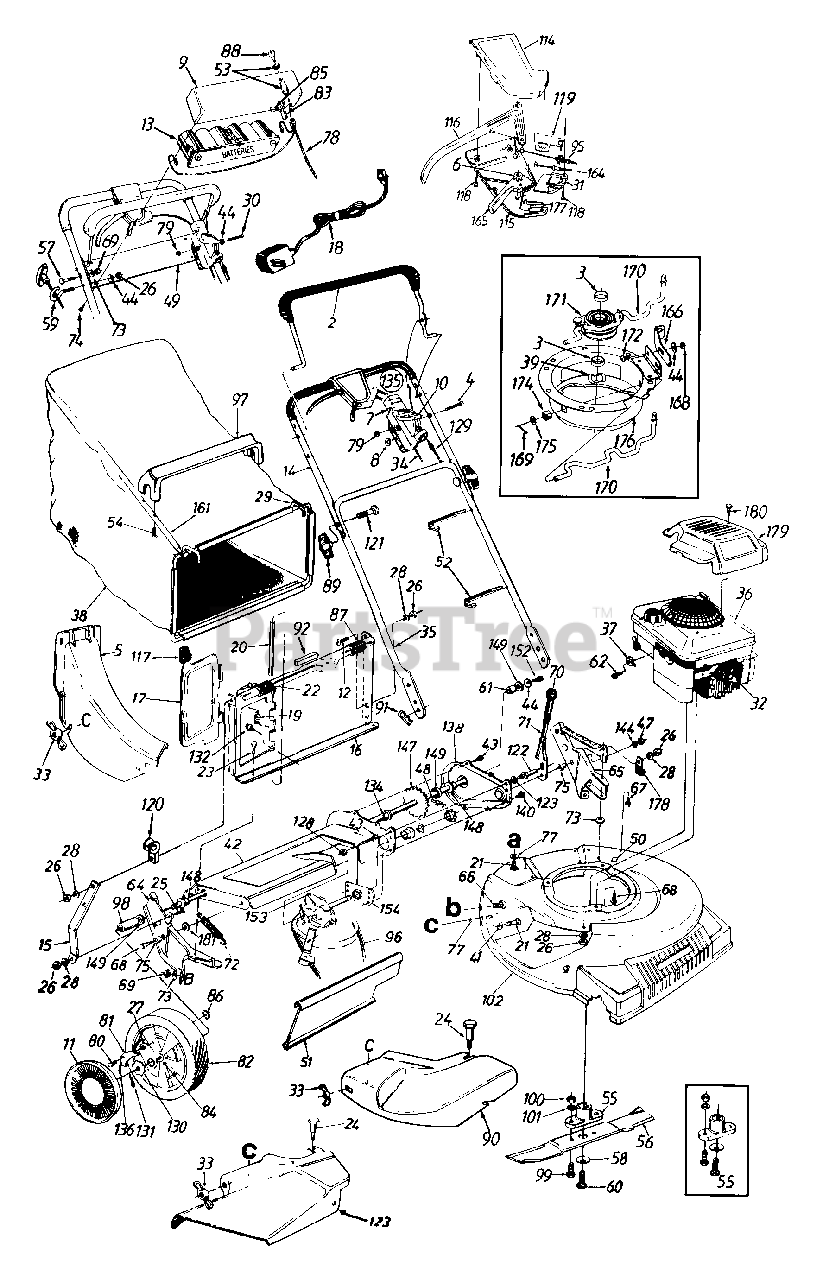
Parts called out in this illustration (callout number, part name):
2	Control Handle
3	Spacer .895" I.D. x 1" O.D.
4	Oval C-Sunk Scr.
5	Rear Discharge Chute Ass'y.
6	3 Tooth Rack Gear Insert
7	Throttle Body
8	Spr. Wash. .66" I.D.
9	Battery Tray
10	Throttle Lever
11	Hub Cap
12	Truss Mach. Scr. 1/4-20 x .62"
13	Battery Pack - 12 Volt
18	Battery Charge
19	Torsion Spring
20	Pivot Pin
21	Carriage Bolt 1/4-20 x .62"
22	Truss Mach. Scr. 1/4-20 x .75"
23	Hex AB - Tap Scr. 1/4-20 x .38"
24	Shoulder Bolt Special
25	Hex Bolt 1/4-20 x .62" Lg.
26	Hex Nut 1/4-20 Thd.
27	Pawl Plate
28	L-Wash. 1/4" I.D.
30	Hex Bolt 1/4-20 x 2" Lg.
31	S.P. Control Cover
32	Spark Plug Insulator
33	Wing Nut
34	Throttle Cable 61"
36	Engine
37	Casing Clamp
38	Grass Bag
39	Wave Wash. .88" I.D. x 1.38" O.D.
41	FI-Wash. .344" I.D. x .62"
44	Bell-Wash. 1/4" I.D.
47	Hex Patch L-Nut 3/8-24 Thd.
48	#48 Chain .500" Pitch x 30 Links
51	Rear Flap
52	Cable Tie
53	Ignition Switch
54	Hex AB-Tap Scr. #12 x 1.25"
55	Blade Adapter Kit
56	21" Mulching Blade
57	Curved Carr. Bolt 5/16-18 x 1.38" Lg.
58	Bell-Wash. .39" I.D.
59	Rope Guide
60	Hex Bolt 3/8-24 x 1.5"
61	Spacer .513" I.D.
62	Hex Wash. Hd. Scr. #10-32 x .62" Lg.
64	R.H. Handle Wheel Brkt. Ass'y.
65	L.H. Handle Wheel Brkt. Ass'y.
66	Carriage Bolt 5/16-18 x .62"
67	Hex B-Tap Scr. 5/16-18
68	Hex TT-Tap Scr. 3/8-16
69	Hex Nut 5/16-18 Thd.
71	Height Adj. Lever
72	Extension Spring 3.80" Lg.
73	Bell-Wash. 5/16" I.D.
74	Truss Mach Tap Scr. 1" Lg.
75	Shld. Spacer .5" Dia.
77	Bolt Retainer 1/4 x .50" O.D.
78	Wire Harness
79	Hex L-Nut 1/4-20 Thd.
80	Shld. Scr. 342" Dia. x .268
81	Pawl - R.H
82	Wheel Ass'y Comp
84	Sleeve Bearing 1/2" I.D.
85	Fuse Holder
86	Flat Nut 1/4-20 Thd.
87	Panel Clip
88	Ignition Key
89	Hand Knob
90	Mulching Plug
91	Hairpin Clip
92	Foam Strip 1/4" x 1" Lg.
95	S.P. Cable - 50" Lg.
96	"V"-Belt
97	Bag Handle
98	Sleeve .526" I.D.
99	Hex Bolt 3/8-24 x 1.0" Lg.
100	Hex Nut 3/8-24 Thd.
101	L-Wash. 3/8" I.D.
115	Self-Propelled Control Cover
116	Control Lever
117	Door Grip
118	Fl-"C"-Sunk Hd Tap Scr. #10 x .75" Lg.
119	6-Speed Rack Cable Brkt
120	Rope Guide
121	Curved Hd. Bolt 5/16-18 x 2" Lg.
122	Shld. Pin 1.43" Lg.
123	L-Wash. 3/8" I.D.
128	Hex Jam Nut 3/8-24 Thd.
129	Control Cable - 44"
130	Ratchet Wheel 1.62" O.D.
131	Cotter Pin 1/8" Dia. x 1"
132	Hex B-Tap Scr #10 x .38" Lg.
134	Hex Flange Bearing
135	Throttle Box Comp.
136	Spring - Nylon
144	FI-Wash. .385" I.D. x .87"
147	Rear Shaft Ass'y. 21.94" Lg.
148	Hex Flange Brg. .506" I.D.
149	FI-Wash. .531" I.D. x .930"
152	Hex Bolt 1/4-20 x .62" Lg. (Grade 5)
153	Transmission Comp.
164	Spd. Control Cable - 50" Lg.
165	6-Spd. Shift Lever
169	Cot-Pin 3/32" Dia. x .75" Lg.
170	Shift Rod
171	Pulley Ass'y.
172	Carr. Bolt 1/4-20 x .5" Lg.
174	Flanged Bushing
175	FI-Wash. .328" I.D. x .68" O.D.
176	Housing Ass'y
177	Shift Lever Spring
179	Engine Cover
180	Screw #10 x 1.25" Lg
181	Fl-Wash. .383" I.D. x 1" O.D.
